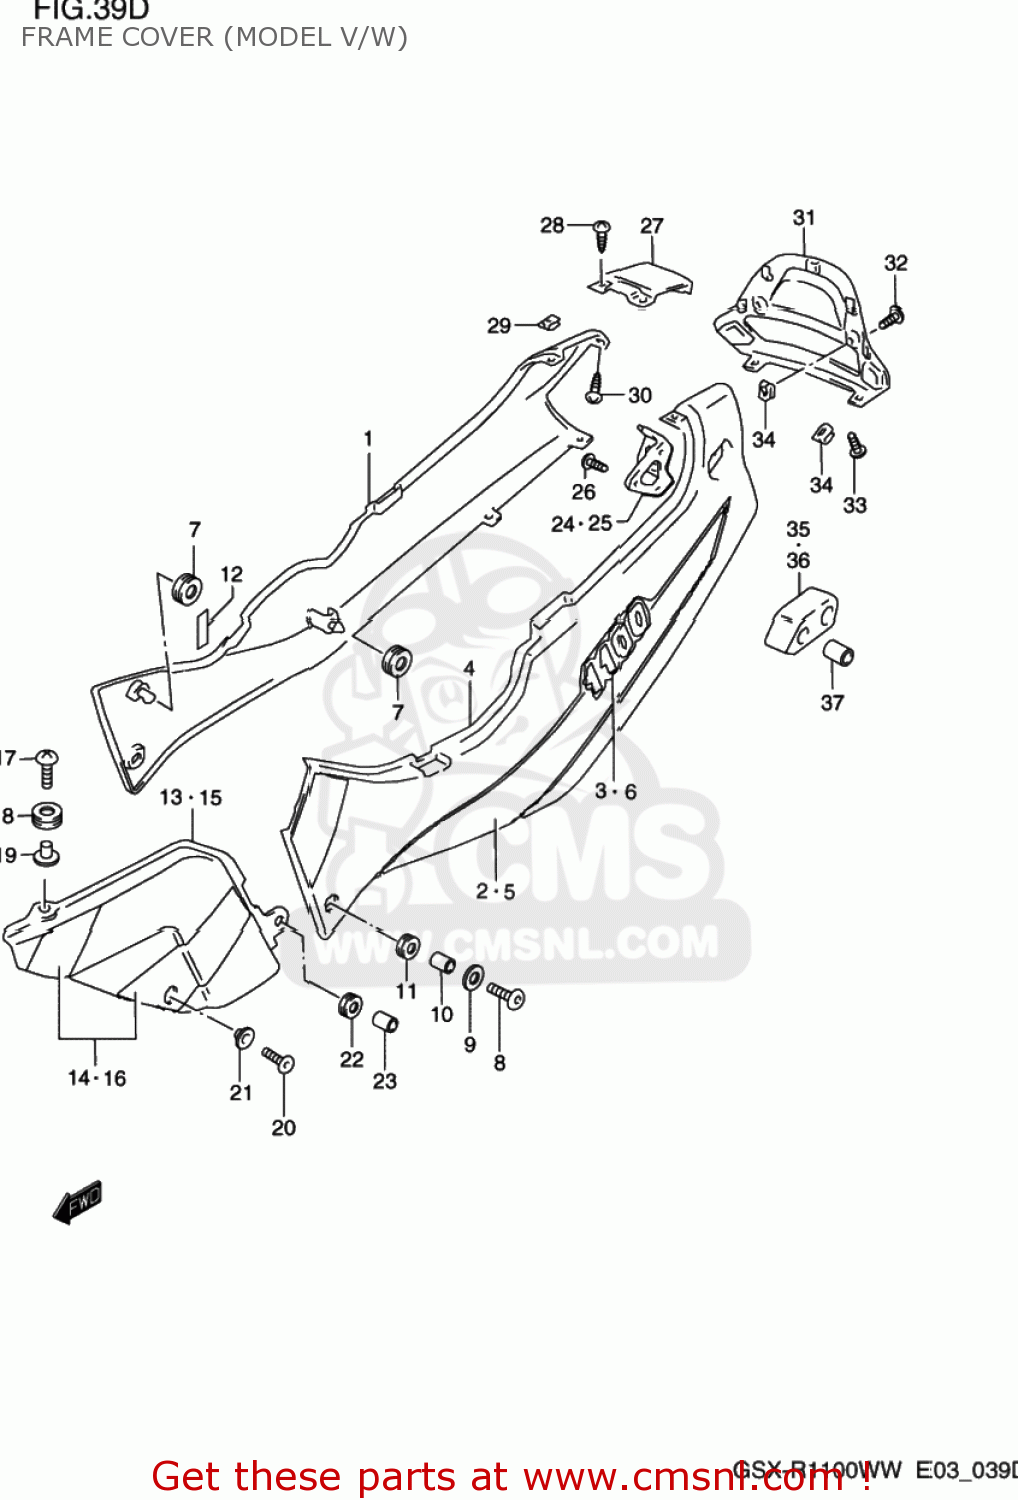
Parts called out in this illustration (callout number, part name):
1	COVER ASSEMBLY,FRAME,RIGHT
2	TAPE SET,FRAME COVER,RIGHT
3	EMBLEM,FRAME COVER,R
4	COVER ASSEMBLY,FRAME,LEFT
5	TAPE SET,FRAME COVER,LEFT
6	EMBLEM,FRAME COVER,L
7	CUSHION
8	SCREW(6X30)
9	WASHER
10	SPACER(6.5X9X9)
11	CUSHION
12	CUSHION
13	COVER ASSY,FRAME BODY,R
14	TAPE SET,FRAME COVER B
15	COVER ASSEMBLY,FRAME BODY
16	TAPE SET,FRAME COVER B
17	SCREW(6X25)
18	CUSHION
19	WASHER
20	SCREW(5X14)
21	WASHER
22	CUSHION
23	SPACER(6.5X9X9)
24	BRACKET,RR COMBINATION LAMP,L
25	BRACKET,RR COMBINATION LAMP,L
26	SCREW
27	COVER ASSY,FRAME CTR
28	SCREW 5X12
29	NUT
30	SCREW
31	COVER,FRAME RR
32	SCREW(5X12)
33	SCREW 5X12
34	NUT
35	CUSHION,PILLION RIDER HANDLE,R
36	CUSHION,PILLION RIDER HANDLE,L
37	SPACER (8.5X16X37)
